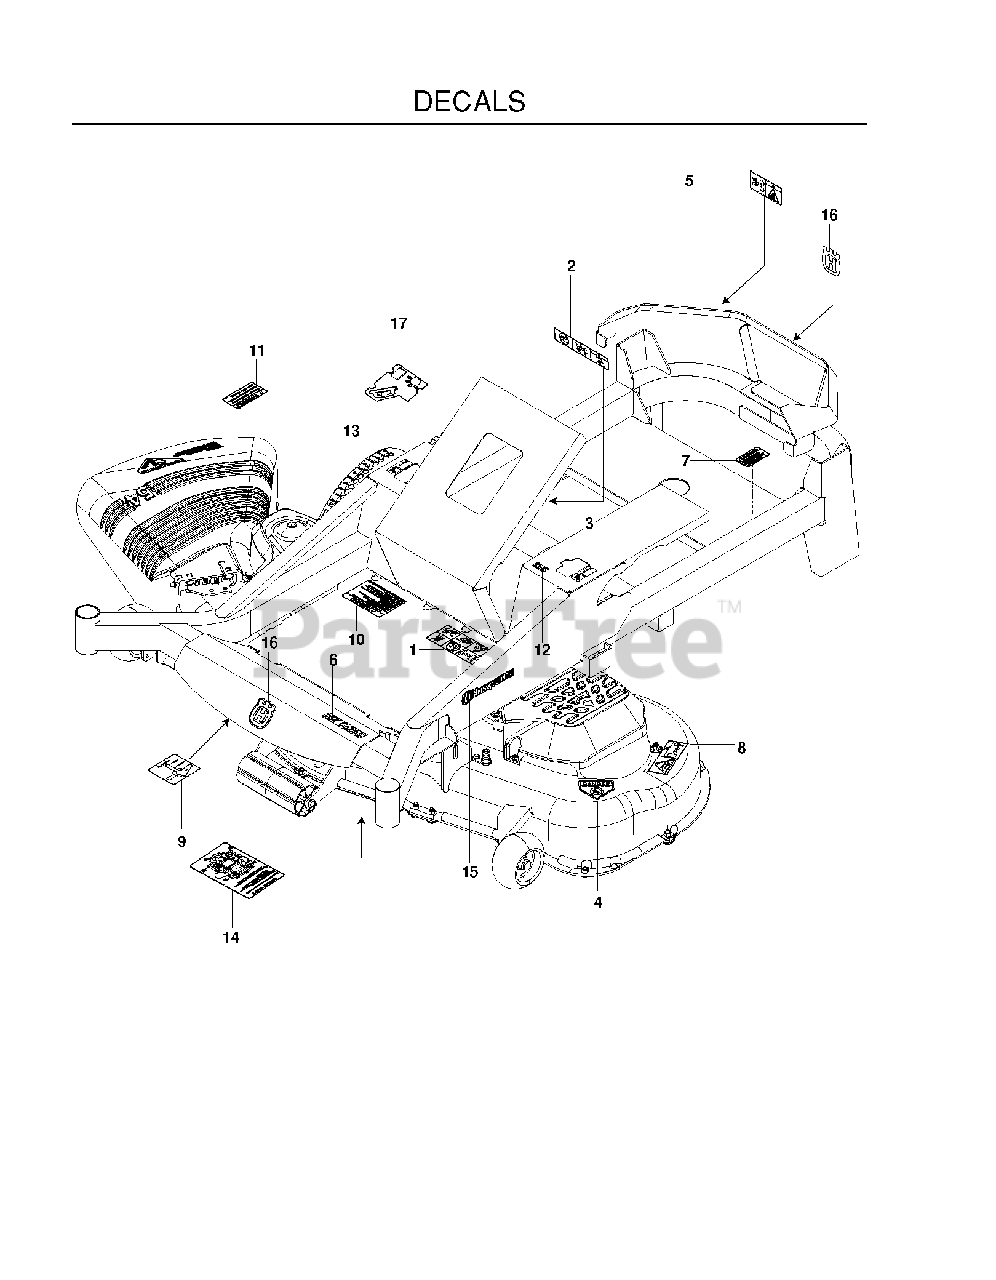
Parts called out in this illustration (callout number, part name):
1	DECAL, WARNING
2	EURO DECAL-BATTERY WARNIN6
3	DECAL, MOTION CONTROL
4	DECAL, CPSC
5	DECAL, BELT DRIVE
6	DECAL, MZ5424S
7	DECAL, PROP. 65
8	DECAL, EURO SEVERING
9	DECAL, BELT ROUTING
10	DECAL, WARNING
11	DECAL, CAUTION
12	DECAL, F.S.T.
13	DECAL, HEIGHT ADJUST
14	DECAL, SERVICE
15	RP.DECAL.BADGE.170MM.TEXTLOGO
16	DECAL.AUGER.HUSQ.CROWN.SNOW
17	DECAL, CONSOLE HUS
